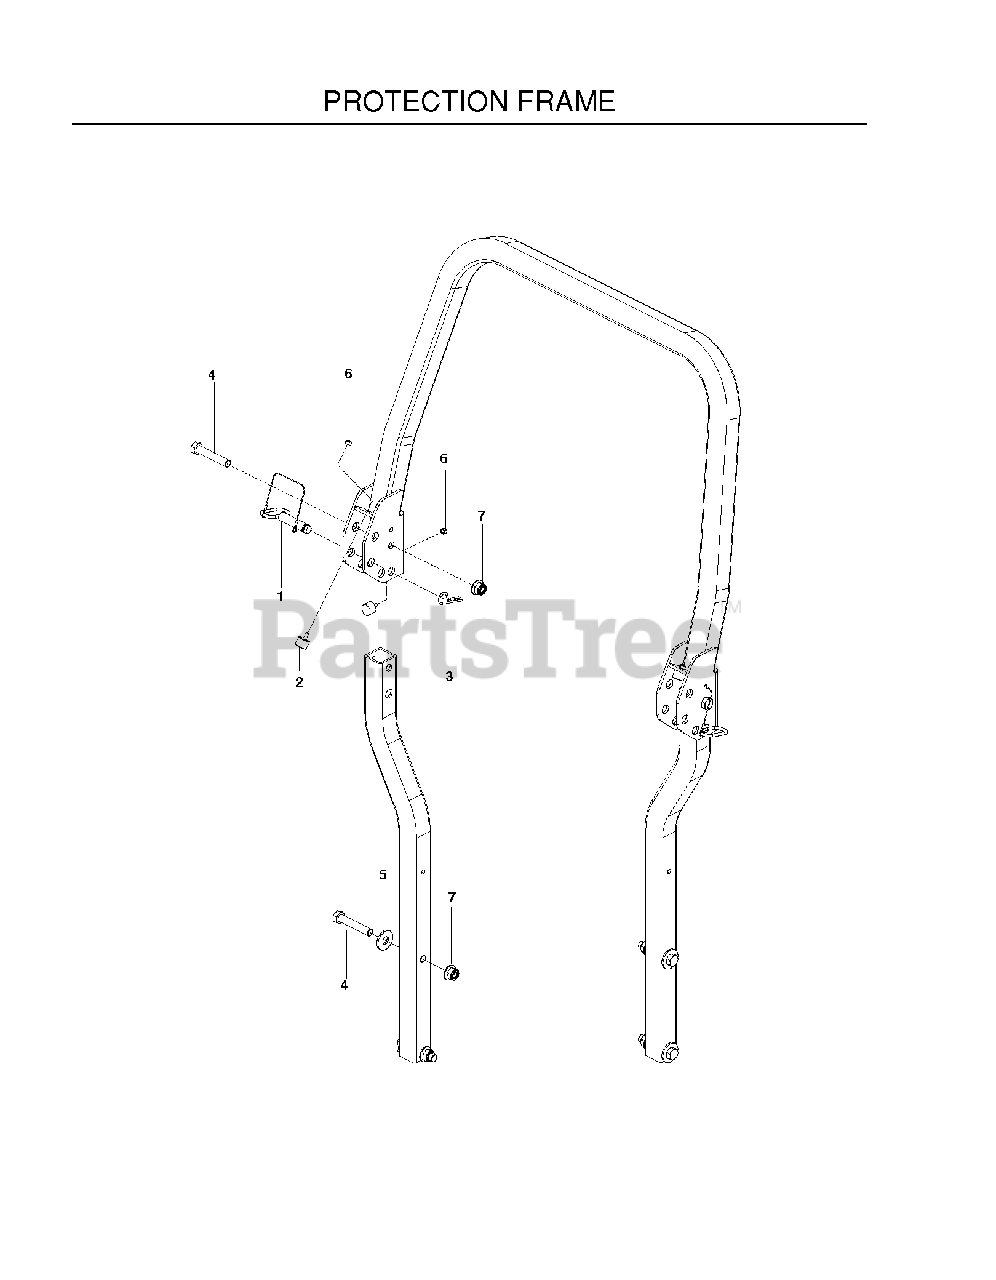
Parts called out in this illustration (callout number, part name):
2	BUMPER, MALE STUD, 1/4-20
3	PIN HAIR .148 X 2-15/16 #210
4	5/8-11 X 3-1/2 HHB GRADE 5
5	WASHER, 5/8 FLAT
6	RP_NUT 1/4-20 NYLOC
7	NUT 5/8-11 FLG NYLOC ZD
